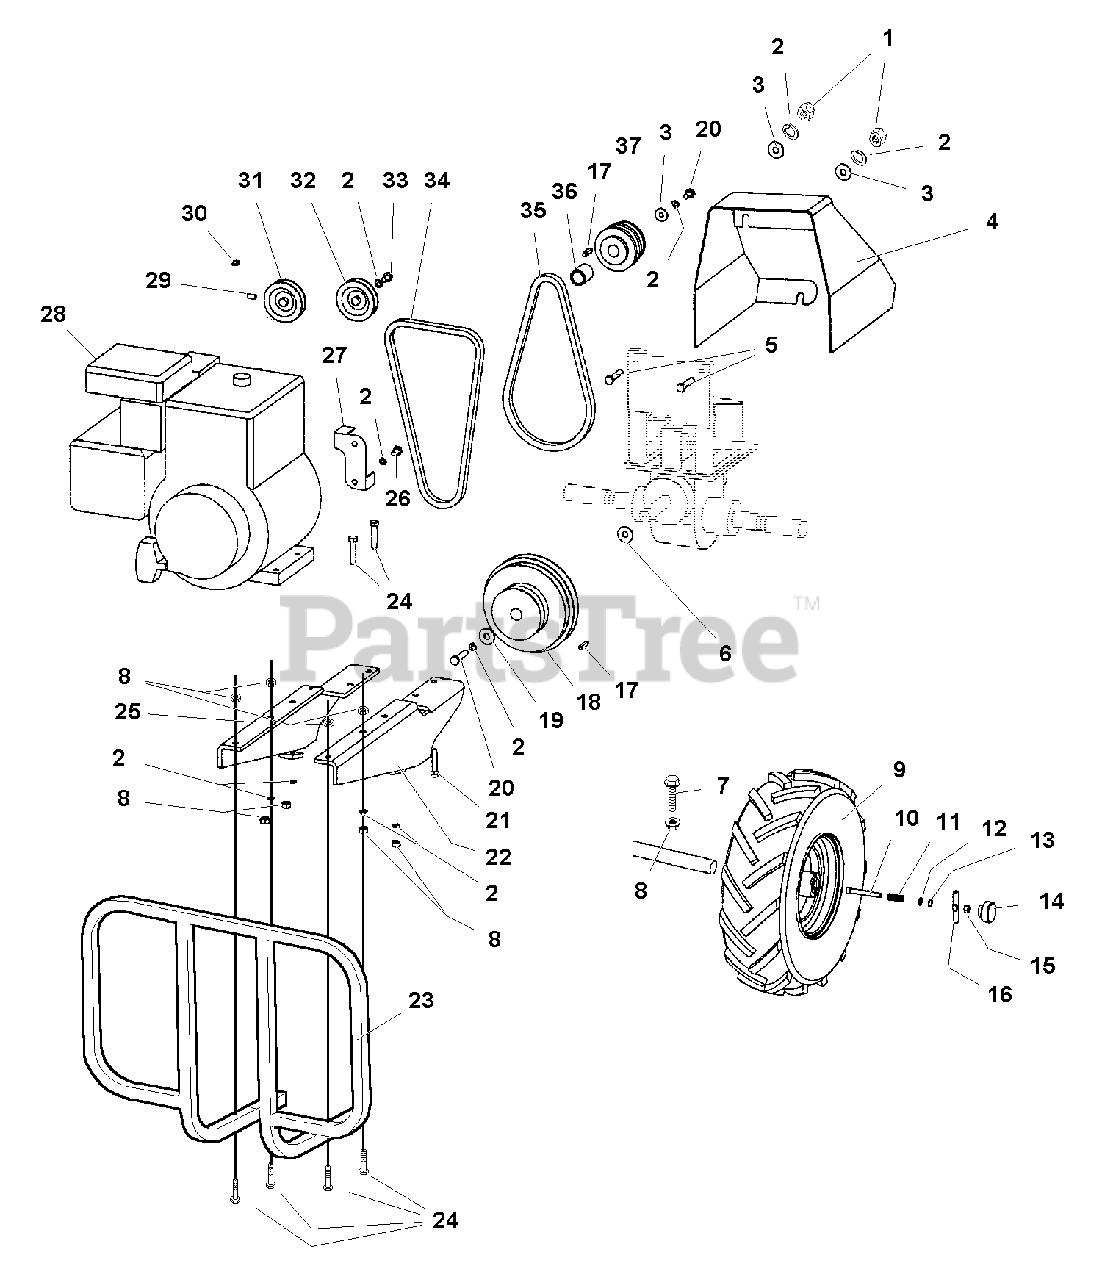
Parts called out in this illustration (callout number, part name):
1	NUT, Hex 5/16" - 18
2	LOCKWASHER, Spring 5/16"
3	WASHER, 5/16"
4	COVER, Belt
5	CAPSCREW, Hex Head 5/16-18 x 2 G5
6	WASHER, 5/8"
7	CAPSCREW, Hex Flange Head, 5/16"- 18 x 3/4"
8	NUT, Hex Flange 5/16"- 18 Two, Way Lock
9	WHEEL & TIRE ASSEMBLY, Tiller LH
9	WHEEL & TIRE ASSEMBLY, Tiller RH
10	CAPSCREW, Hex Socket Head, 1/4"- 20 x 2-5/32"
12	WASHER, 1/4"
14	KNOB, Wheel Lock Out
15	NUT, Hex Keps 1/4" - 20
16	KNOB, Lock Out Set of Two
17	KEY, Parrallel
18	PULLEY, Transmission
20	CAPSCREW, 5/16"- 24 x 3/4" G5
21	CAPSCREW, Hex Socket Head, 5/16"- 18 x 11/4" G8
22	BRACKET, Engine Mount LH
23	BUMPER, Guard
24	CAPSCREW, 5/16"- 18 x 1 3/4" G5
25	BRACKET, Engine Mount RH
26	CAPSCREW, 5/16"- 24 x 1/2"
27	GUIDE, Belt Forward
29	SCREW, Set 1/4"- 20 x 1/4"
30	KEY, Woodruff
31	PULLEY, Engine, Reverse
33	CAPSCREW, Hex Head, 5/16"- 24 x 1-1/2"
34	V-BELT, Reverse
35	V-BELT, Forward
36	SPACER, Engine Pulley
37	PULLEY, Engine, Forward
